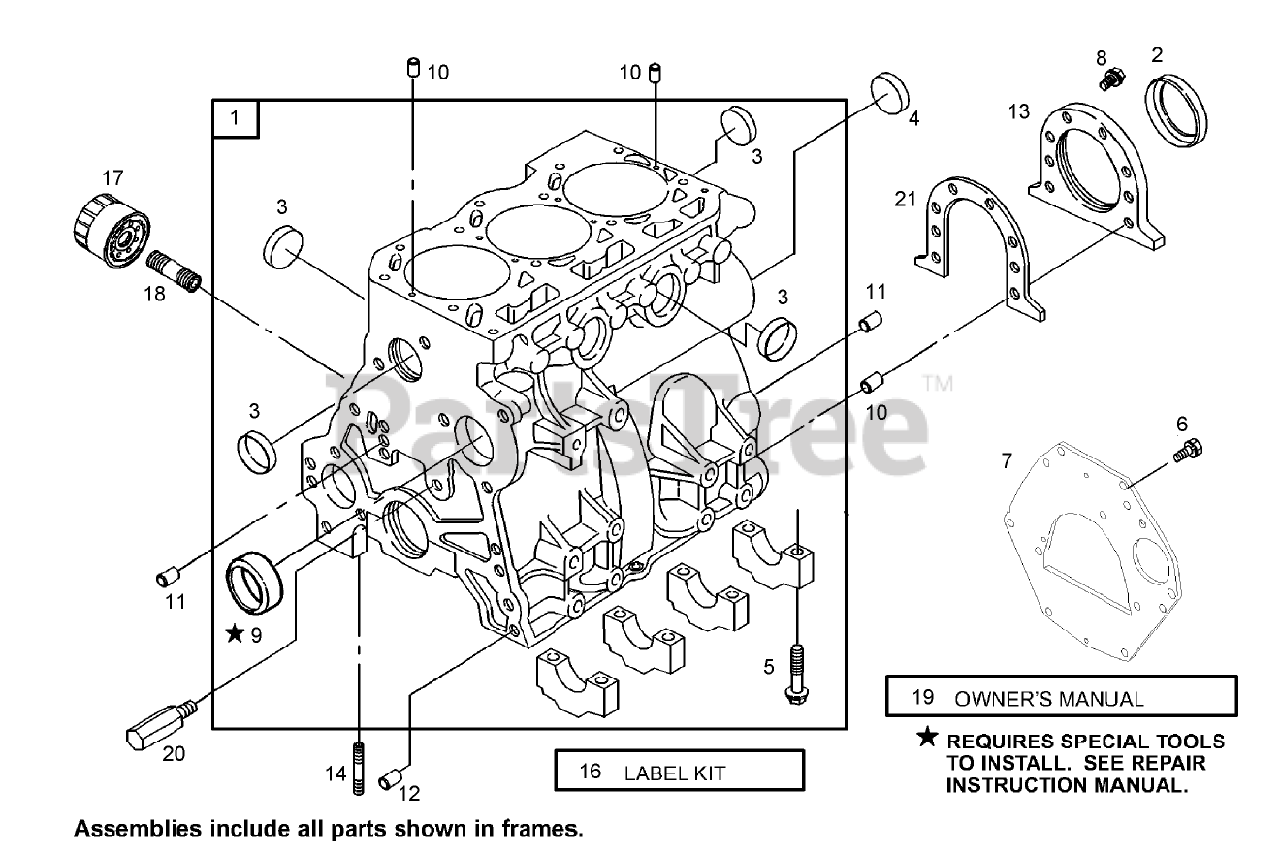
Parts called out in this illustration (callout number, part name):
1	CYLINDER ASM
2	SEAL-OIL
3	PLUG-WELCH
4	PLUG-WELCH (CAM)
5	SCREW-HEX
6	SCREW-HEX
7	PLATE-END, REAR
8	SCREW-HEX
9	BUSHING
10	PIN-LOCATING
11	PIN-LOCATING
12	PIN-LOCATING
13	RETAINER-SEAL
14	STUD-METRIC
16	KIT-LABEL
18	ADAPTER-FILTER, OIL
19	MANUAL-ENGINE
20	NOZZLE-OIL
21	GASKET-RETAINER
